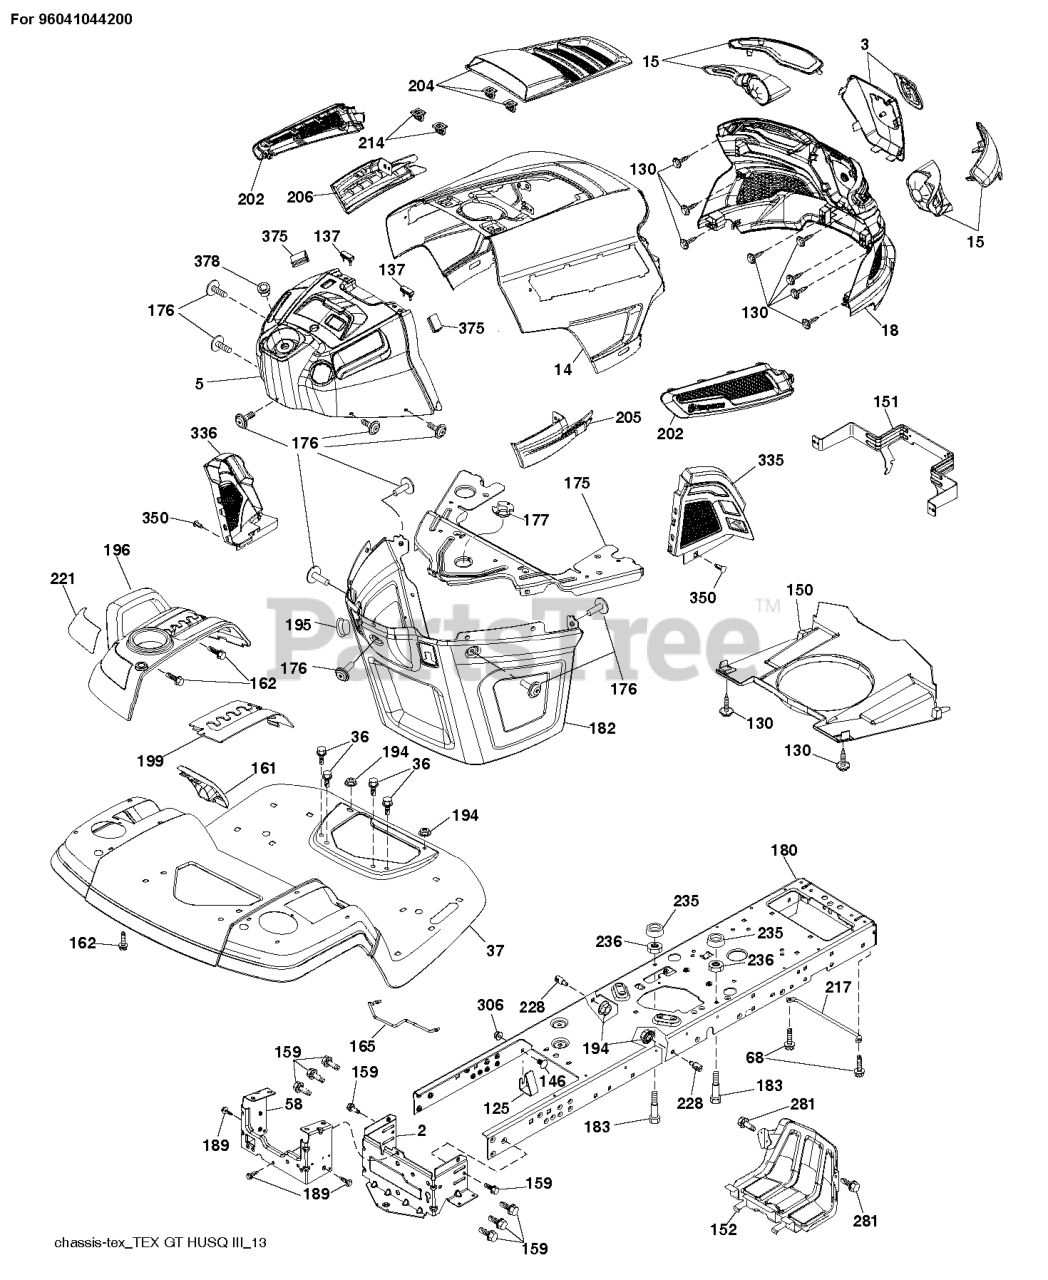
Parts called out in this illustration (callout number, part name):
2	DRAWBAR.LOWER.2PC.18/22
3	Covers
14	HOOD.ASM.HUSQVARNA.GT.TEX.ORAN
15	Service Kit
36	SCREW 5/16"
37	FENDER.PNT.TX.GT.CH/FW/DL.HUSQ
58	DRAWBAR.UPPER.2PC,LRG.FENDER
125	CLIP.FUEL.LINE
137	BUMPER DASH
146	BOLT.RDHD.SHT.SQNK.3/8-16X5/8
150	AIR.DUCT.GTV.BLACK
151	BRACKET.PIVOT.HOOD.GT.HUSQ.II
152	SHIELD.BROWNING.PNT.GT.V2
159	SCREW, 3/8-16X3/4
161	CONSOLE.WINDOW.FUEL.HUSQ.GT
165	SUPPORT.TANK.REAR.B/TE
175	PLATE.PNT.CROSSMEMBER.HUSQ/PRE
176	SCREW.#10-24X5/8.RN.QU
177	BUSHING STEERING
180	CHASSIS.LT/GT.BOLTED
182	DASH.LOWER.COMMON.12V.ADAPTOR
189	SCREW
195	PLUG.HOLE.DASH.LOWER.12V.BLK
196	SUBASM.CONSOLE.HUSQ.GT.DECKLFT
199	PLATE.DECK.LIFT.HUSQVARNA.GT
202	Vents
205	SIDE.TRIM.RH.GT.HUSQ.II
206	SIDE.TRIM.LH.GT.HUSQ.II.GRAY
214	CLIP.RETAINER.TINNER.
217	ROD.PIVOT.HOOD
221	REFLECTOR.LH.TEX GT HU
228	STUD.W/"D"ANTI-ROTATION
236	NUT.CENTERLOCK.5/16-
281	SCREW 3/8-16X1
306	NUT LOCK FLG 3/8-16 UNC
335	COVER.LOWER.DASH.RH.BLACK
336	COVER-LH.LOWER.DASH.GT2.BLACK
350	CLIP.X-MAS.TREE
375	BUMPER CLIP-ON. DASH 1"
378	BUSHING FLANGE; PLASTIC
